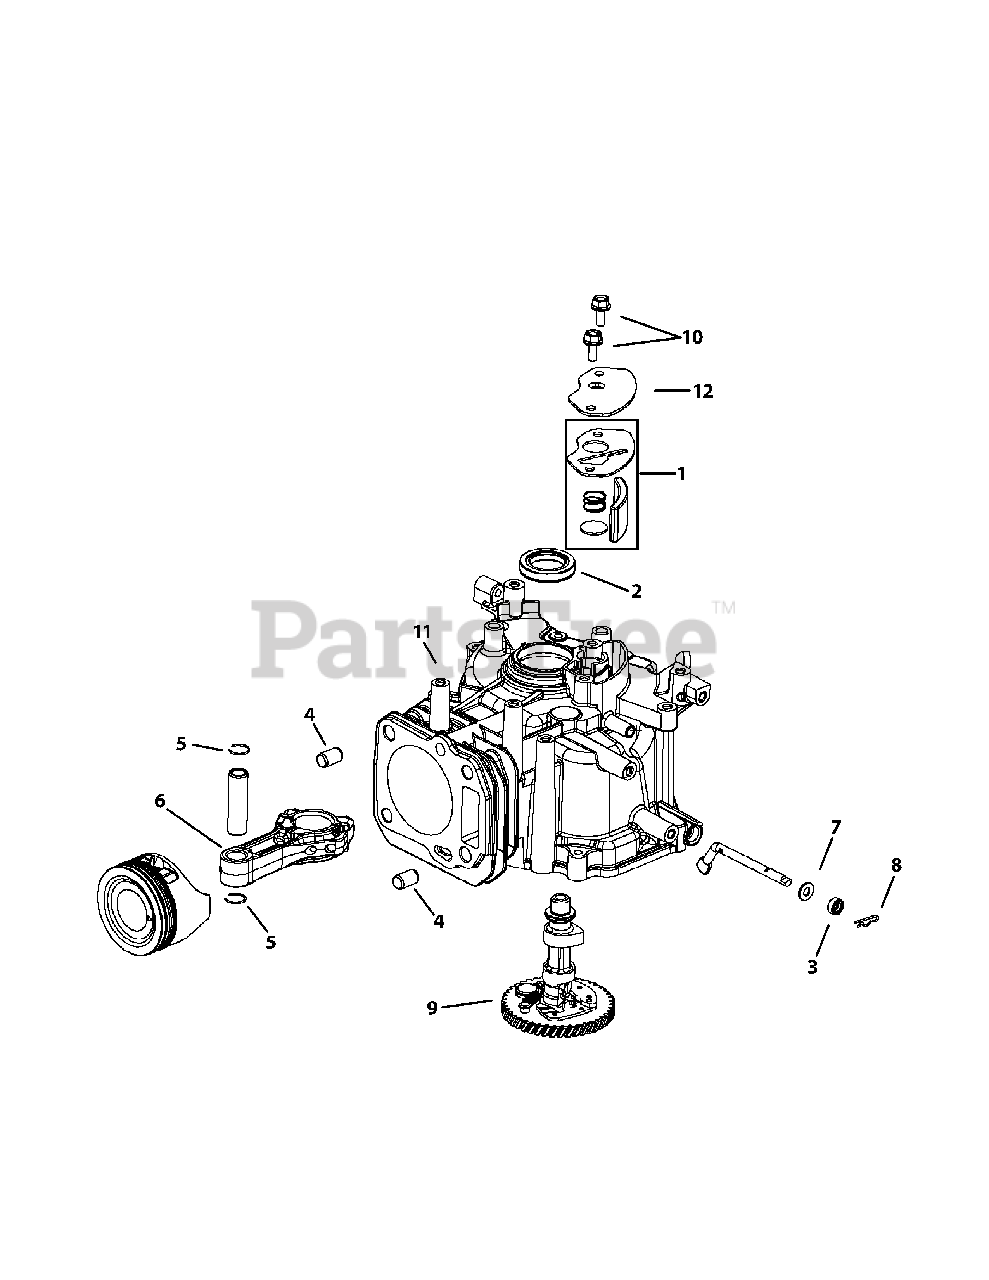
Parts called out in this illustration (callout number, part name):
1	Breather Filter Kit
4	Cylinder Head Dowel
5	Piston Pin Retainer
6	Connecting Rod
7	Flat Washer, 13 mm
8	Governor Shaft Clip
9	Camshaft Assembly
10	Hex Flange Screw, M6
12	Breather Cover
